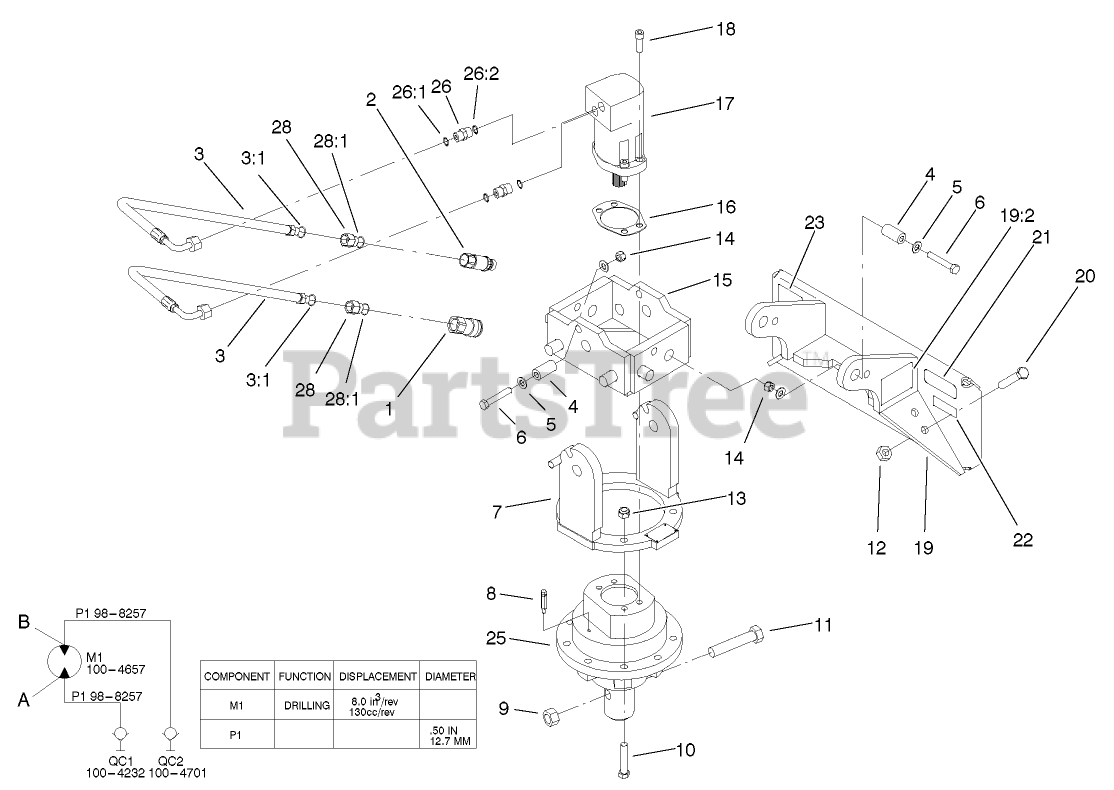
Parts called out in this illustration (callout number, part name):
1	COUPLER-FACE, FLUSH
2	NIPPLE-CONNECT, PRESSURE
3	HOSE - HYDRAULIC
3:1	O-RING
4	PIN - PIVOT
5	WASHER-FLAT
6	SCREW-HH
7	HOUSING - DRIVE
8	BREATHER ASM
9	NUT-HEX
10	SCREW-HH
11	SCREW
12	NUT-HEX
13	LOCKNUT
14	NUT-LOCK, NI
15	SWIVEL GIMBEL ASM
16	GASKET
17	HYDRAULIC MOTOR ASM
18	SCREW-HSH
19	AUGER MOUNT ASM,
19:2	DECAL-WARNING
20	SCREW-HH
21	DECAL-ATTACHMENT, DINGO
22	DECAL-INFO
23	DECAL
25	DRIVE-GEAR, PLANETARY
26	FITTING-STRAIGHT
26:1	O-RING
26:2	O-RING
28	ADAPTER-HYD
28:1	O-RING
